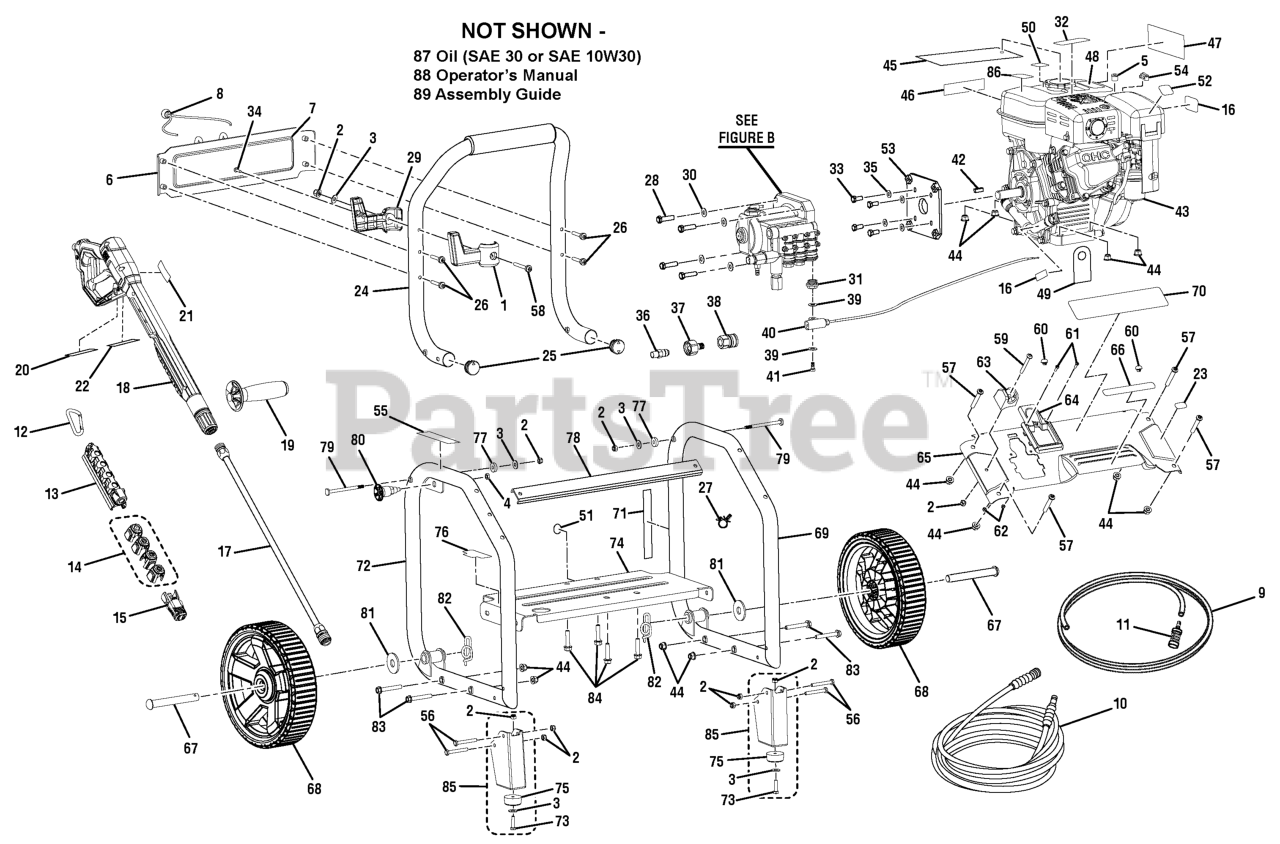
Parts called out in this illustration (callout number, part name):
1	WAND HOLDER (FRONT)
2	LOCK NUT (1/4-20)
3	WASHER (1/4 IN.)
4	LOCK NUT (1/2-20)
5	SWIVEL BUSHING
6	LOGO PLATE
7	PERFORMANCE LABEL
8	BUNGEE CORD AND BEAD ASSEMBLY
9	INJECTION HOSE
10	HIGH PRESSURE HOSE (30 FT.)
11	INJECTION HOSE FILTER
12	SPRING CLIP
13	STORAGE HOLDER
14	NOZZLE KIT
15	SOAP BLASTER NOZZLE
16	SQUEEZE TRIGGER LABEL
17	SPRAY WAND
18	TRIGGER HANDLE ASSEMBLY
19	AUXILIARY HANDLE ASSEMBLY
20	TRIGGER GUARD WARNING LBL F/S
21	TRIGGER GUARD WARNING LABEL
22	MAX PRESSURE LABEL
23	IDLE CONTROL LABEL
24	HANDLE ASSEMBLY
25	HANDLE TUBE CAP
26	BOLT (1/4 X 42 MM, PAN HD.)
27	CABLE CLAMP
28	BOLT (3/8-16 X 1-3/8 IN HEXHD)
29	WAND HOLDER (BACK)
30	WASHER (3/8 IN.)
31	THREADED VALVE PLUG
32	DO NOT MIX LABEL
33	BOLT (5/16-24 X 3/4 IN HEX HD)
34	SCREW (#8)
35	WASHER (5/16 IN.)
36	THERMAL RELEASE VALVE
37	GARDEN HOSE COUPLER W/FILTER
38	QUICK DISCONNECT (FEMALE)
40	THROTTLE CONTROL ASSEMBLY
41	THROTTLE CONTROL BOLT(SPECIAL)
42	OUTPUT SHAFT KEY (27 MM)
43	SP170 Hori. Engine (Parts available at your local Subaru dealer)
44	LOCK NUT (M8 X 1.25 MM)
45	HANG TAG (ENGINE)
46	ADD LUBRICANT LABEL
47	COMBUSTION WARNING LABEL
48	DANGER LABEL (ENGINE)
49	OIL DIPSTICK HANG TAG
50	E-85 LABEL
51	CHECK OIL LABEL
52	HOT MUFFLER LABEL
53	PUMP FLANGE
54	CABLE CLAMP
55	HANDLE RELEASE LABEL
56	BOLT (1/4-20 X 52 MM HEX HD.)
57	BOLT (M8 X 70 MM HEX SOC. HD.)
58	SCREW (1/4-20 X 2.27 IN.)
59	SCREW (1/4-20 X 2.1 T30 TORX)
60	BUMPER HANDLE
61	SCREW (M4 X 12 MM HEX BUTN HD)
62	LOCK NUT (M4)
63	WAND HOLDER
64	TRIGGER HANDLE STORAGE
65	FACE PLATE
66	HOT SURFACE LABEL
69	LEFT FRAME
70	LOGO LABEL
71	QUICK START LABEL (ENGINE)
72	RIGHT FRAME ASSEMBLY
73	BOLT (1/4-20 X 1 IN.)
74	ENGINE PLATE
75	WEAR PAD
76	QUICK START LABEL (PUMP)
77	WASHER (OD20 X ID8 X 4.5T)
79	CONNECTOR PIN (1/4 IN.)
80	HANDLE KNOB
81	WASHER (1/2 IN.)
82	HITCH PIN
83	BOLT (M8 X 55 MM HEX HD.)
84	BOLT (M8 X 45 MM HEX HD.)
85	FOOT ASSEMBLY
86	DANGER LABEL (FRENCH)
